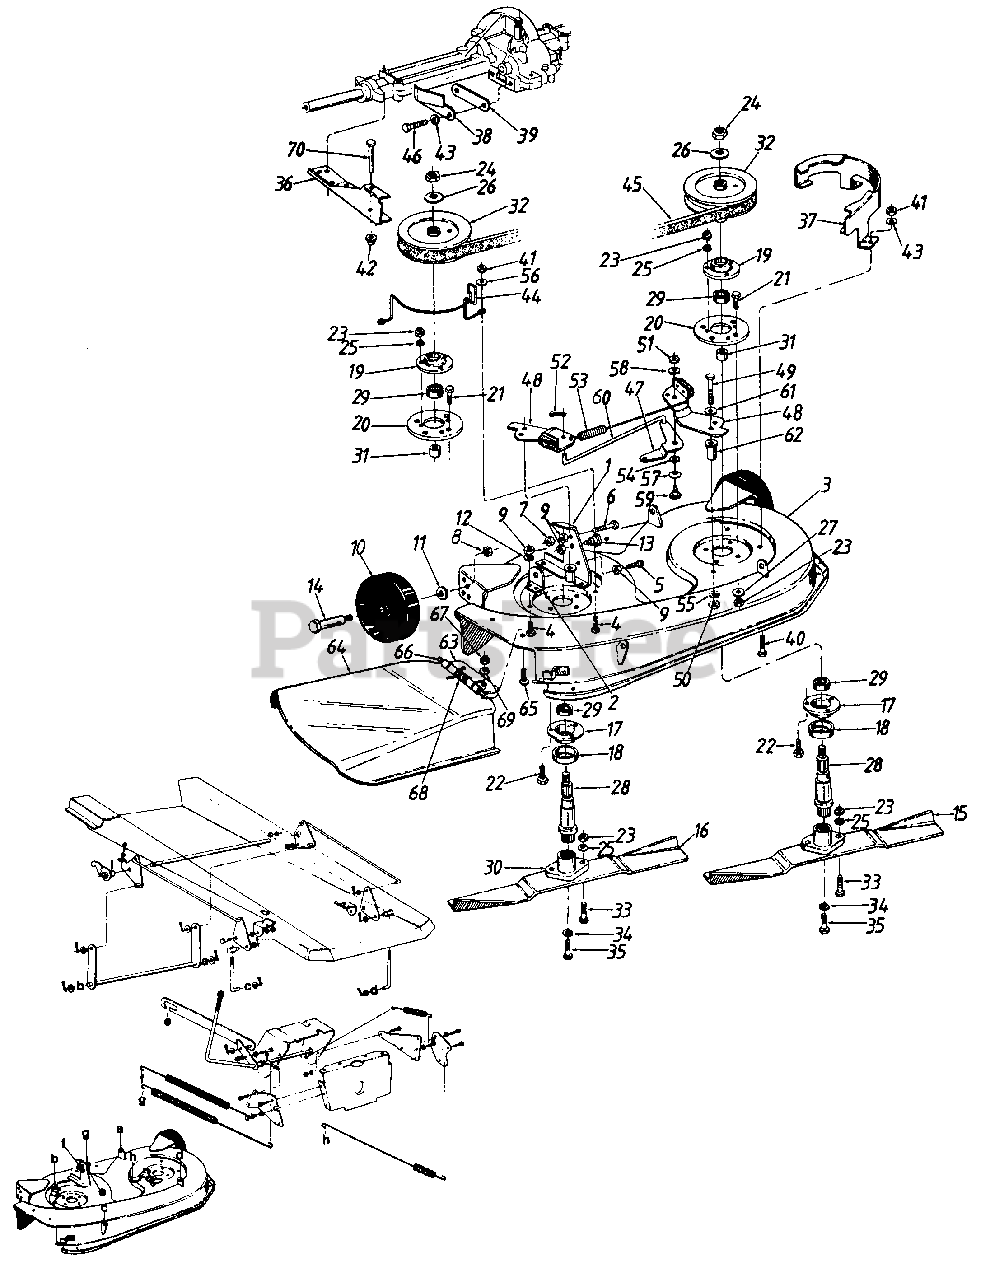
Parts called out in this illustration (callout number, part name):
1	Deck Disengagement Brkt.
2	Rear Deck Brkt.-R.H.
3	38" Deck Ass'y.
4	Hex Bolt 1/4-20 x .62" Lg.
5	Hex TT-Tap Scr. 1/4-20 x .75" Lg.
6	Hex Wash. Hd. Scr. 1/4-20 x 1.5" Lg.
7	Hex L-Nut 1/4-20 Thd.
8	Hex L-Nut 3/8-16 Thd.
9	Hex Nut 1/4-20 Thd.
10	Deck Wheel
11	Bell-Wash .380 I.D. x .88
12	L-Wash 1/4 1. D .
13	Shld Bolt .500 Dia. x .215" Lg.
14	Shld. Bolt .498 Dia. x 1.53" Lg.
15	L.H. High-Lift Blade
16	R.H. High-Lift Blade
17	Bearing Housing
18	Bearing Shield
19	Open Brg. Housing
20	Spindle Mounting Plate
21	Hex Bolt 5/16-24 x .75" Lg.
22	Hex Bolt 5/16-24 x 1.0" Lg. (Special)
23	Hex Nut 5/16-24 Thd.
24	Hex Jam Nut 5/8-18 Thd.
25	L-Wash. 5/16" I.D.
26	L-Wash. 5/8" I.D.
27	Bell-Wash. .345 I.D. x .88
28	Blade Spindle
29	Ball Bearing
30	Blade Adapter
32	5" Dia. Pulley
33	Hex Bolt 5/16-24 x 1.0" Lg. (Special)
34	L-Wash. 3/8" I.D. H.D.
35	Hex Bolt 3/8-24 x 1.0" Lg.
36	Lower Outside Belt Guard
37	Belt Guard Deck-R.H.
38	Lower Inside Belt Guard
39	Belt Guard Spacer
40	Hex Bolt 1/4-20 X .62" Lg.
41	Hex Nut 1/4-20 Thd.
42	Speed Nut 1/4" Rod
43	L-Wash. 1/4" I.D.
44	Deck Belt Guard
46	Hex Bolt 1/4-20 x .75" Lg.
47	Deck Brake Bracket
48	Deck Brake Brkt. Ass'y.
49	Hex Bolt 5/16-24 x 2" Lg.
50	Hex Nut 5/16-24 Thd.
51	Hex Nut 1/4-20 Thd.*
52	Cotter Pin 1/16 Dia.
53	Extension Spring
54	Fl-Wash. .406 I.D. x 1.00
55	L-Wash. 5/16" I.D.
56	Bell-Wash. .265 I.D. x .75
57	Washer-Bowed
58	L-Wash. 1/4" I.D.
59	Shld Bolt .375 Dia. x .181" Lg.
60	Deck Control Rod
61	Shld. Spacer.27" Lg.
62	Spacer 1.46" Lg.
63	Chute Brkt.
64	Chute
65	Truss-Mach. Scr. 1/4-20 X .75" Lg.
66	Hinge Pin
67	Hex Nut 1/4-20 Thd.
68	Torsion Spring 1.14" Lg.
69	L-Wash. 1/4" I.D
